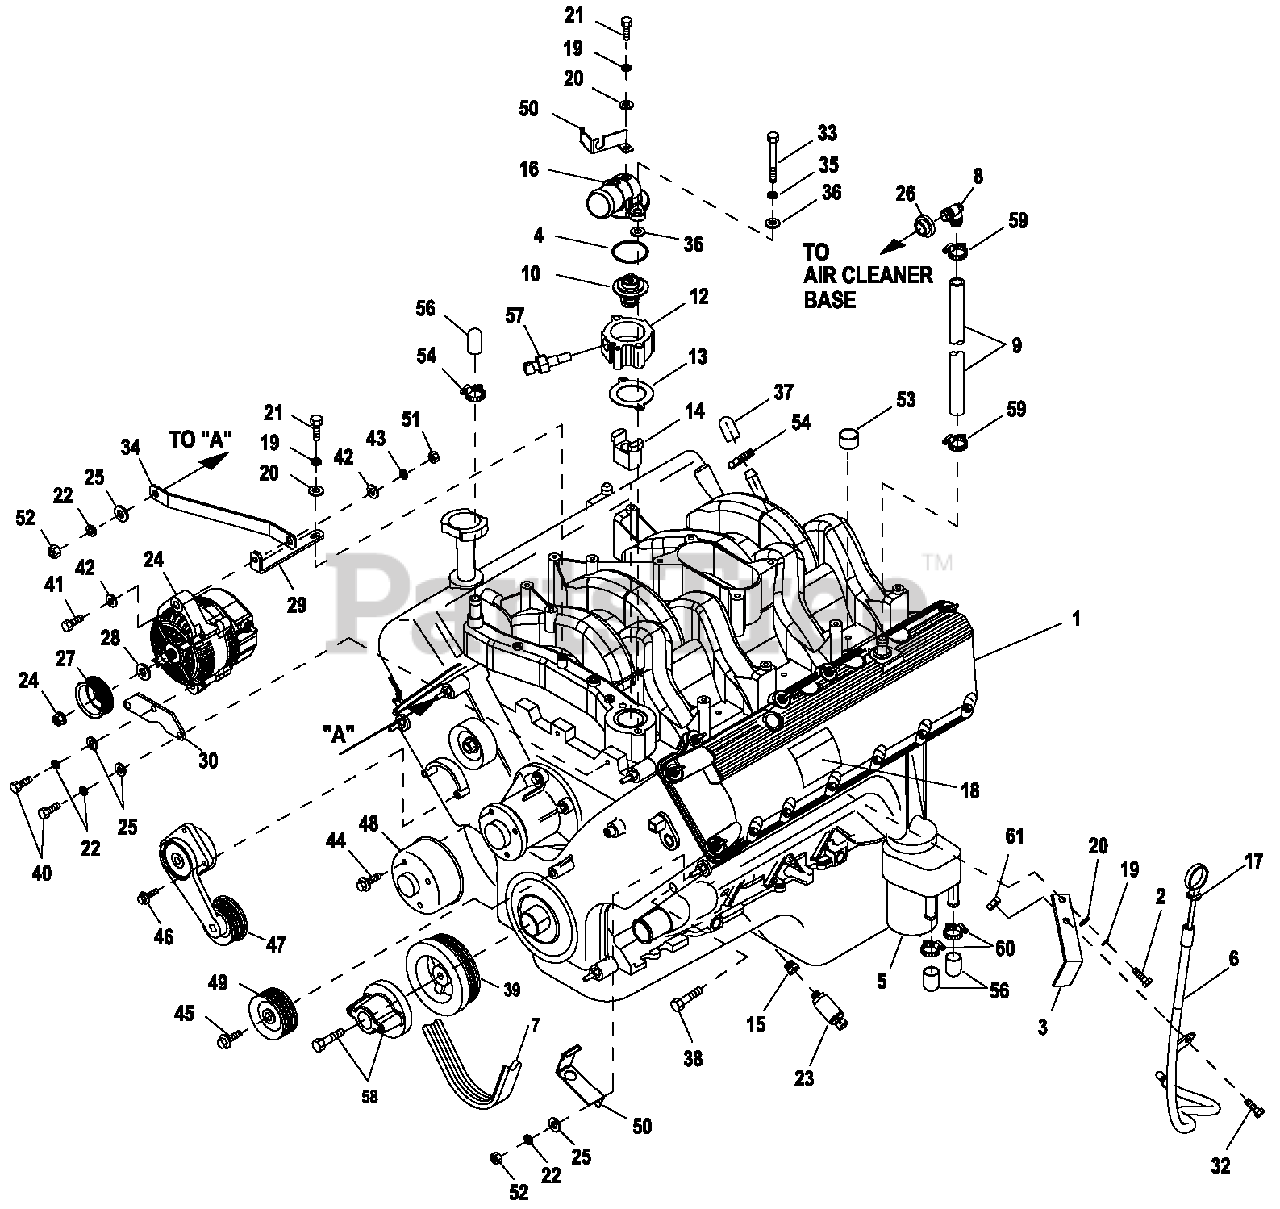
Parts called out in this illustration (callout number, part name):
1	ENGINE G5.4L G3 2009
2	SCREW H HC M6-1.0X20 C8.8
3	BRACKET DIPSTICK TUBE
4	GASKET T HERMOSTAT HOUSING
5	OIL FILTER V-10 ENGINE
6	TUBE DIPSTICK
7	BELT SERPENTINE 65.0" (1800 RPM)
8	BARBED EL 90 3/4 PLASTIC
9	HOSE 3/4 ID SAE-30R2 (16.751G)
10	T H ERMOSTAT ASSY
12	ADAPTER T HERMOSTAT 4.6L G3
13	GASKET TH ERMOSTAT 4.2L
14	SPACER COOLANT BYPASS
15	BS HG RDCRH EX 1/4 TO 1/8
16	CONNECTION WATER OUTLET
17	DIPSTICK
18	DECAL EPA STATIONARY EMERGENCY
19	WAS HER LOCK M6-1/4
20	WAS HER FLAT 1/4 ZINC
21	SCREW H HC M6-1.0X20 G8.8
22	WAS HER LOCK M8-5/16
23	SENDER OIL PRESSURE 1/8"NPT
24	ALTERNATOR DC W/OUT PULLEY
25	WAS HER FLAT 5/16 ZINC
26	GROMMET
27	PULLEY 80 OD DC ALTERNATOR (1800RPM)
28	SPACER DC ALTERNATOR PULLEY
29	BRKT DC ALTERNATOR UPPER
30	BRKT DC ALTERNATOR LOWER
32	SCREW HW H TFM6-1.0X16
33	SCREW H HC M8-1.25X 140 G8.8
34	BRACKET DC ALT STABILIZER
35	WAS HER LOCK M8-5/16
36	WAS HER FLAT 5/16-M8ZINC
37	CAP ANTIFREEZE 5/8"ID X 1.2"LG
38	SCREW H HC M10-1.5X60 C8.8
39	REWORK HARMONIC BALANCER 5.4L
40	SCREW H HC M8-1.25X20 G8.8
41	SCREW H HC M10-1.5 X 45 G8.8 FT
42	WAS HER FLAT 3/8-M10ZINC
43	WAS HER LOCK M10
44	SCREW WP PULLEY M8-1.25 X 19
45	BOLTH EX FL HD M8-1.25 X 28
46	BOLTH EX FL HD M8-1.25 X 31
47	TENSIONER ENG. AUTOMATIC BELT
48	PULLEY WATER PUMP
49	PULLEY GROOVED ENGINE IDLER
50	BRACKET SIGNAL CONDITIONER
51	NUTHEXM10-1.5 G8 YELCHR
52	NUT HEXM8-1.25G8 YELCHR
54	CLAMP HOSE #10.56-1.06
56	CAP RUBBER
57	TEMPERATURE SENDER, DELPHI
58	REWORK HARMONIC BALANCER 5.4L
59	CLAMP HOSE #10.56-1.06
60	CLAMP HOSE #12.50-1.25
61	NUT HEX M8-1.25 G8 CLEAR ZIN
